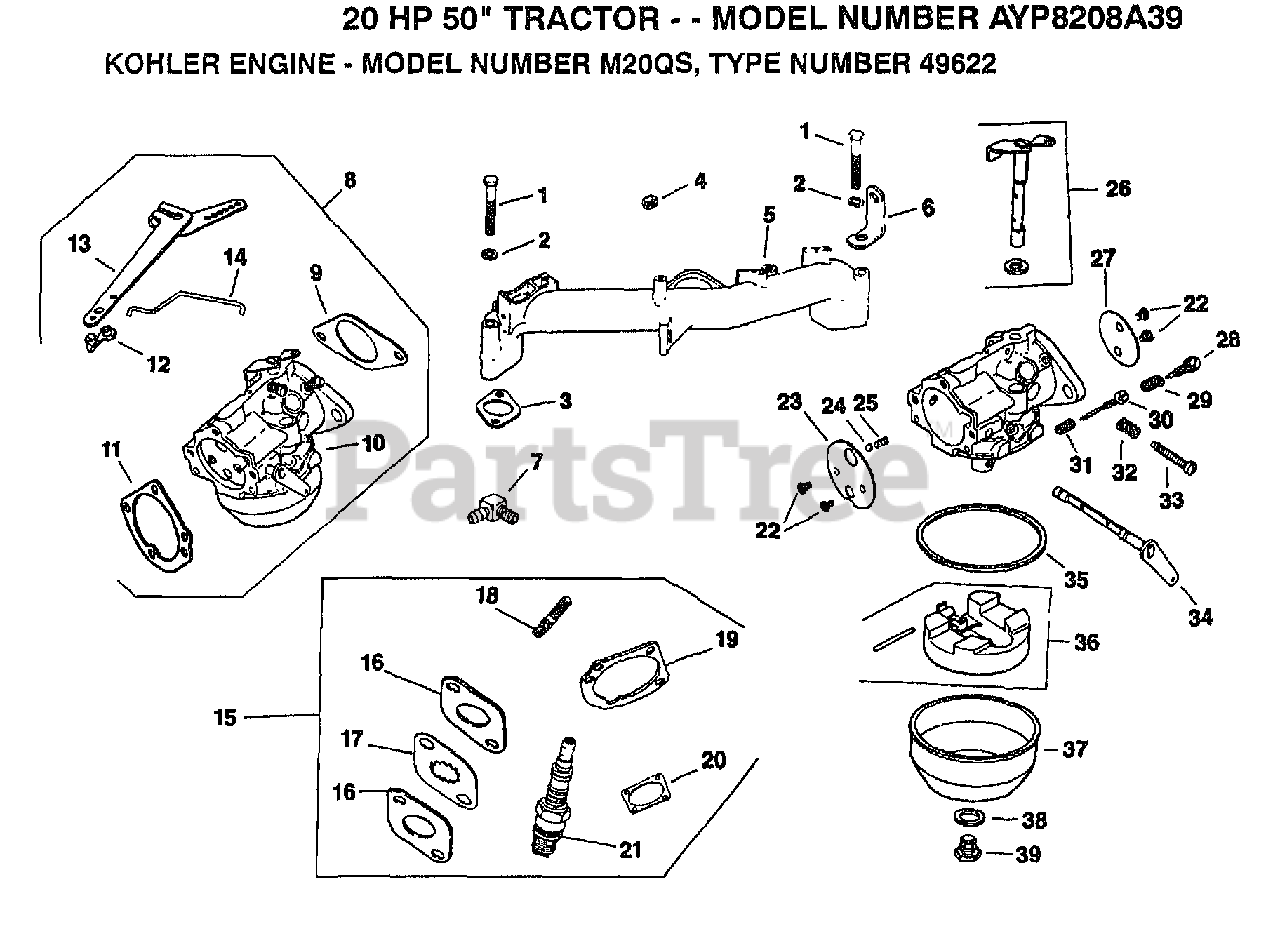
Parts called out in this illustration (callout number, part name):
1	SCREW
2	WASHER
3	GASKET, INTAKE
4	NUT
5	MANIFOLD, INTAKE
6	STRAP, LIFTING
7	CONNECTOR, HOSE
8	KIT, CABURETOR WITH GASKET
9	GASKET
10	CARBURETOR ASSEMBLY
11	GASKET, AIR CLEANER ELBOW
13	ARM, GOVERNOR
14	KIT, GOVERNOR LINKAGE
15	KIT, CARBURETOR BAFFLE
16	GASKET
17	BAFFLE, CARBURETOR
19	GASKET, AIR CLEANER ELBOW
20	GASKET
23	PLATE, CHOKE
24	BALL, CHOKE, FRICTION
25	SPRING, CHOKE, FRICTION
26	SHAFT, THROTTLE WITH LEVER AND SEAL
27	PLATE, THROTTLE
28	NEEDLE, IDLE FUEL ADJUST
29	SPRING, IDLE, FUEL
31	SPRING, IDLE SPEED
32	SPRING, IDLE, FUEL
33	NEEDLE, MAIN FUEL
34	LEVER, CHOKE
35	GASKET, BOWL
38	GASKET, BOWL RETAINER SCREW
